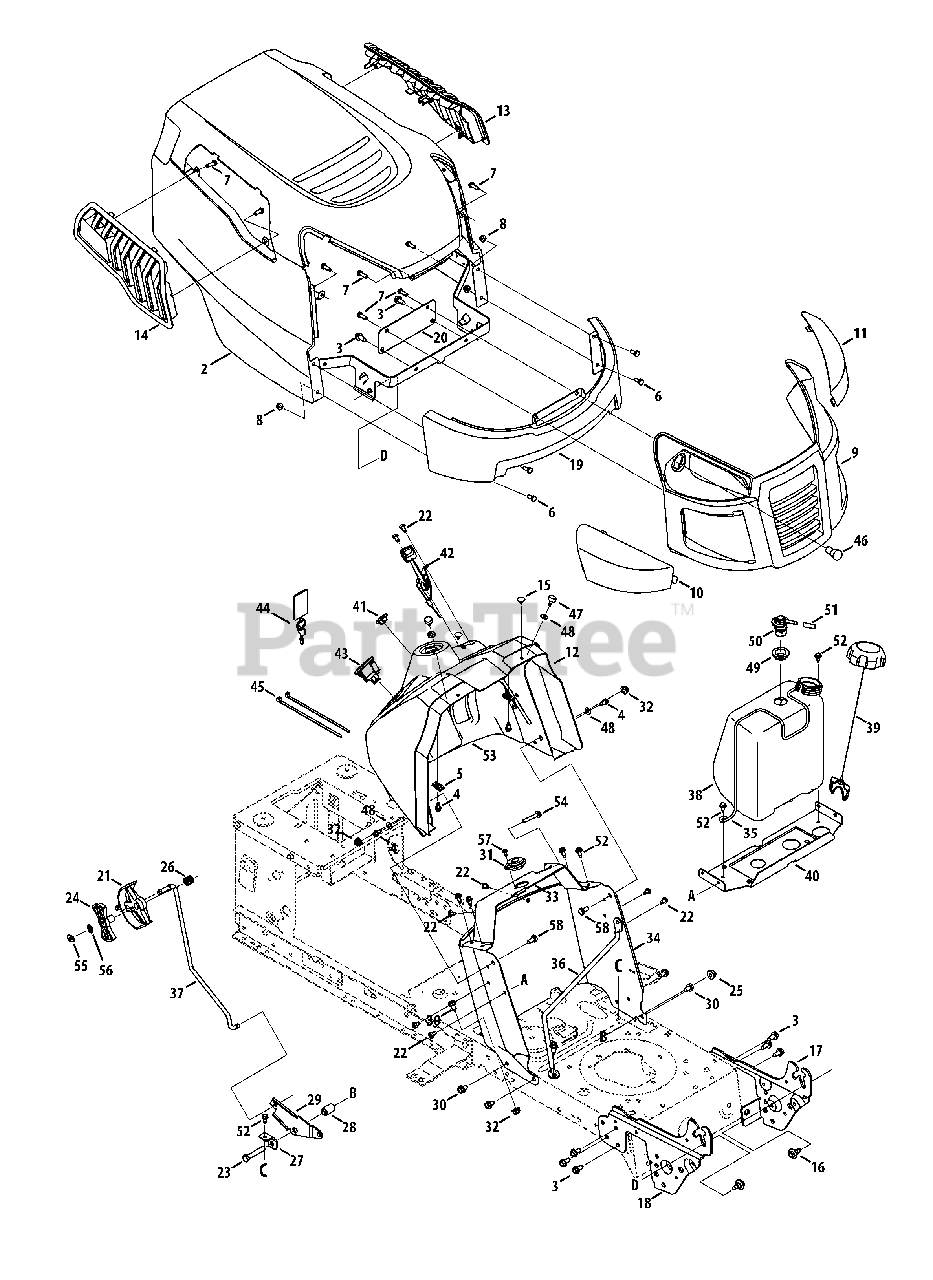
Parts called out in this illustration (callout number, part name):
1	Bulb Socket
2	Hood Assembly
3	Screw, 5/16-18 x .750
4	Hex Washer Screw, 1/4-20 x .500
5	Tin Clip Nut, 1/4-20
6	Hex Screw, 1/4-20 x .620
7	Screw, 1/4 x .750
8	Nut, Hex Flange Insert Lock, 1/4-20
10	Headlight Lens, RH
11	Headlight Lens, LH
12	Dash Collar
13	Hood Scoop, LH
14	Hood Scoop, RH
15	Bumper
16	Shoulder Screw, 5/16-18
17	Left Support Pivot Bracket
18	Right Support Pivot Bracket
19	Lower Grill
20	Lower Grill Bracket
21	Parking Brake Lever
22	Self-Tap Screw, 1/4-20
23	Hex Head Screw, 3/8-16
24	Ferrule, 1/4-20 x 1.00
25	Nut, Hex Flange Insert Lock, 3/8-16
26	Compression Spring
27	Speed Latch Support Tab
28	Flange Spacer
29	Speed latch
30	Self-Tap Screw, 5/16-18
31	Steering Column Bearing
32	Nut, Hex Flange Lock, 5/16-18
33	Steering Support Bracket
34	Dash
35	Fuel Tank Support Rod
36	Dash support Rod
37	Control Rod
38	Fuel Tank
39	Fuel Cap
40	Gas Tank Support Bracket
41	Choke Plug
42	Throttle/Choke Assembly
43	Key Switch Module
44	Key Assembly
45	Cable Tie
46	Headlight Bulb
47	Ratchet Clip, .250 x .500
48	Flat Washer, .25 x .630 x .0515
49	Rubber Grommet
50	Fuel Rollover Valve
51	Vent Hose
52	Hex Washer Screw, 1/4-20 x .625
53	Upper Dash
54	Hex Flange Bolt
55	Top Lock Weldnut
56	Lock Washer
57	Screw, #10
58	Hex Head Screw, 5/16-18
